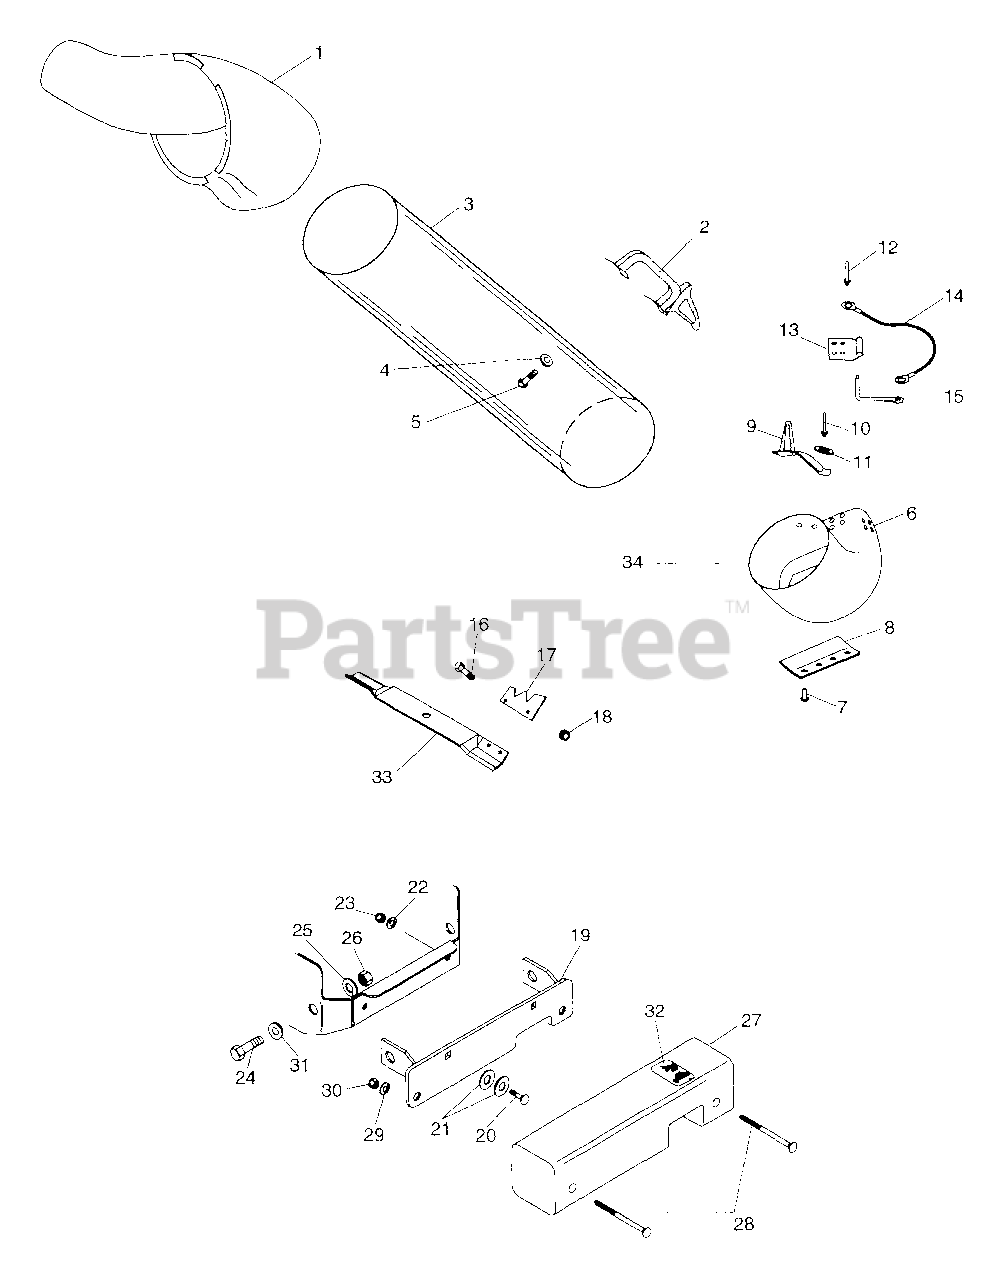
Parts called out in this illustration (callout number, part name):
1	BAGGER BOOT
2	TUBE HANDLE
3	BAGGER TUBE
4	WSHR-FL-STL .268X.562X.046 PL
5	SCR-TAP 10-16X .75 HWH PL SD
6	PAN BOOT ASSEMBLY
7	RVT-TBLR .187X.375 OH ST PL
8	EXTENSION CHUTE
9	TUBE RETAINER
10	RVT-POP.187X.527 DOME ST
11	WSHR-FL-STL .194X.492X.047 PL
12	RVT-POP .187X.402 DOME ST
13	BOOT BRACKET
14	LANYARD
15	PULL PIN
16	BLT-HEX .31-24X.75 GR8
17	SERVICE VANE PACKAGE
18	NUT-LK TOP .312-24 PL GR C
19	ADAPTER
20	BLT-RDHDSQNK .38-16X1.0 PL
21	WSHR-FL-STL .38X.875X.083 PL
22	WSHR-LK .375X.094 MED PL
23	NUT-HEX .375-16
24	BLT-HEX .62-11X1.25 PL GR5
25	WSHR-LK .625X.156 MED PL
26	NUT-HEX .625-11
27	COUNTER WEIGHT
28	BLT-RDHDSQNK .44-14X4.50 PL
29	WSHR-LK-INT .438 YWZC
30	@NUT-HEX .44-14 YWZC
31	WSHR-FL-STL.656X1.312X.095 PL
32	DECAL- HOT SURFACE SYMB.
33	MOWER BLADE
34	MOWER BOOT ASSY- 40"
